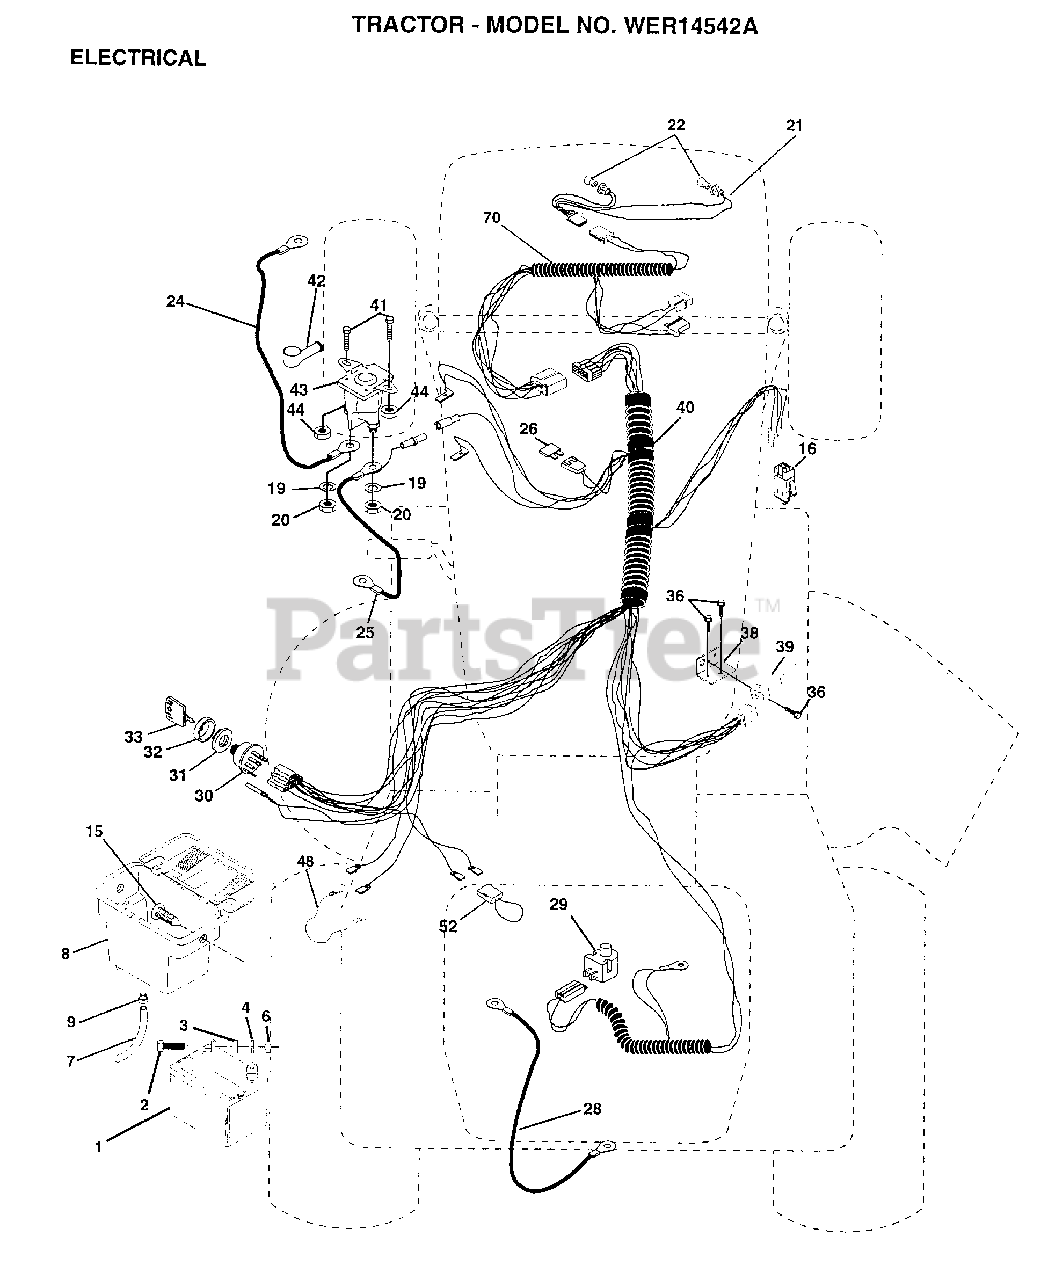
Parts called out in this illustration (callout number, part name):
2	BOLT LT
3	WASHER
4	LOCKWASHER
7	TUBE T
9	HOSE CLAMP T
15	FASTNER.SNAP-IN
16	SWITCH INTERLOCK
20	NUT
21	"HARNESS,LIGHT SOC"
22	HEADLAMP BULB
24	"CABLE T, BATTERY"
25	CABLE.BTRY.6GA.RD
26	FUSE HYT
28	CABLE T
29	SWITCH SEAT
30	SWITCH IGN 4POS
31	NUT IGNITION
32	COVER KEY SWITCH
33	KEY
36	SCREW
38	BRACKET SWITCH IN
39	SWITCH INTERLOCKT
40	HARNESS.IGNITION
41	BOLT HXHD FIN
44	NUT HXKEP 1/4X20
48	ADAPTER AMMETER
52	PROTECTION LOOP
70	HARNESS ENGINE
